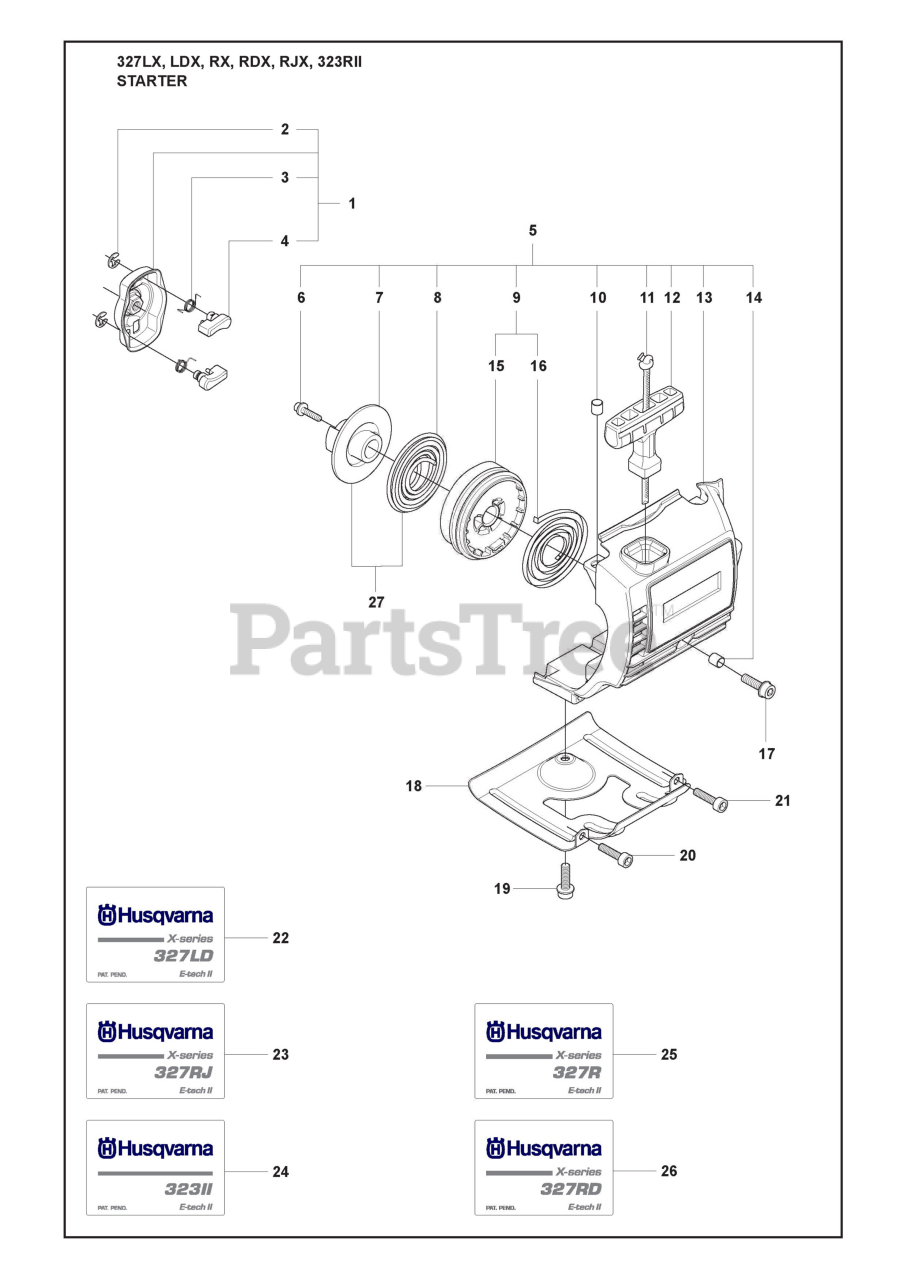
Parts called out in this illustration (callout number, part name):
1	STARTER PAWL BRIDGE
4	STARTER PAWL
5	RP STARTER ASSY
7	DRIVER PULLEY
8	SPRING - DRIVER
9	STARTER PULLEY
10	SPACING SLEEVE
11	STARTER ROPE
12	STARTER HANDLE
13	RP STARTER HOUSING
14	SPACING SLEEVE
15	STARTER PULLEY
17	SCREW
19	SCREW
22	LABEL 327LDX
23	LABEL 327RJ
24	LABEL 323 RII
25	LABEL 327RX
26	LABEL 327RDX
